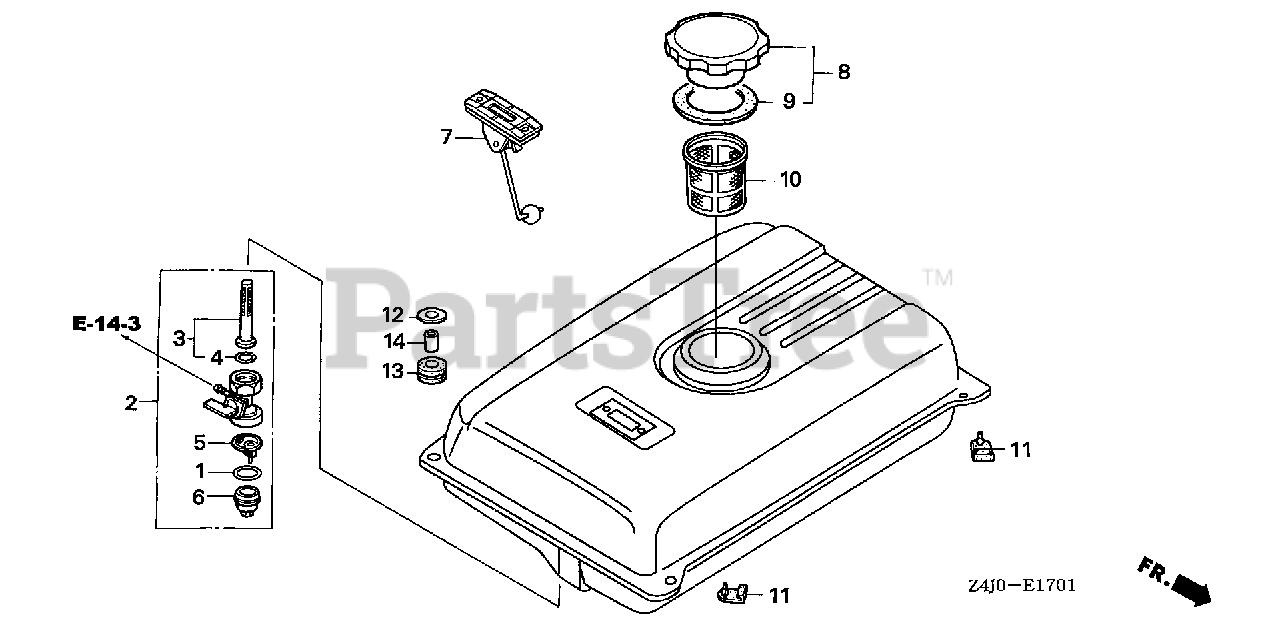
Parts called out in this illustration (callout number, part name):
1	GASKET, FUEL STRAINER CUP
2	PETCOCK ASSY.
3	SCREEN SET, FUEL STRAINER
4	O-RING (9.0X1.3)
5	FILTER, CUP
6	CUP, FUEL STRAINER
7	METER ASSY., FUEL
8	CAP, FUEL FILLER
9	GASKET, FUEL FILLER CAP
10	FILTER, FUEL
11	RUBBER, TANK MOUNTING
12	WASHER, TANK CUSHION
13	RUBBER, TANK CUSHION
14	COLLAR, TANK CUSHION
